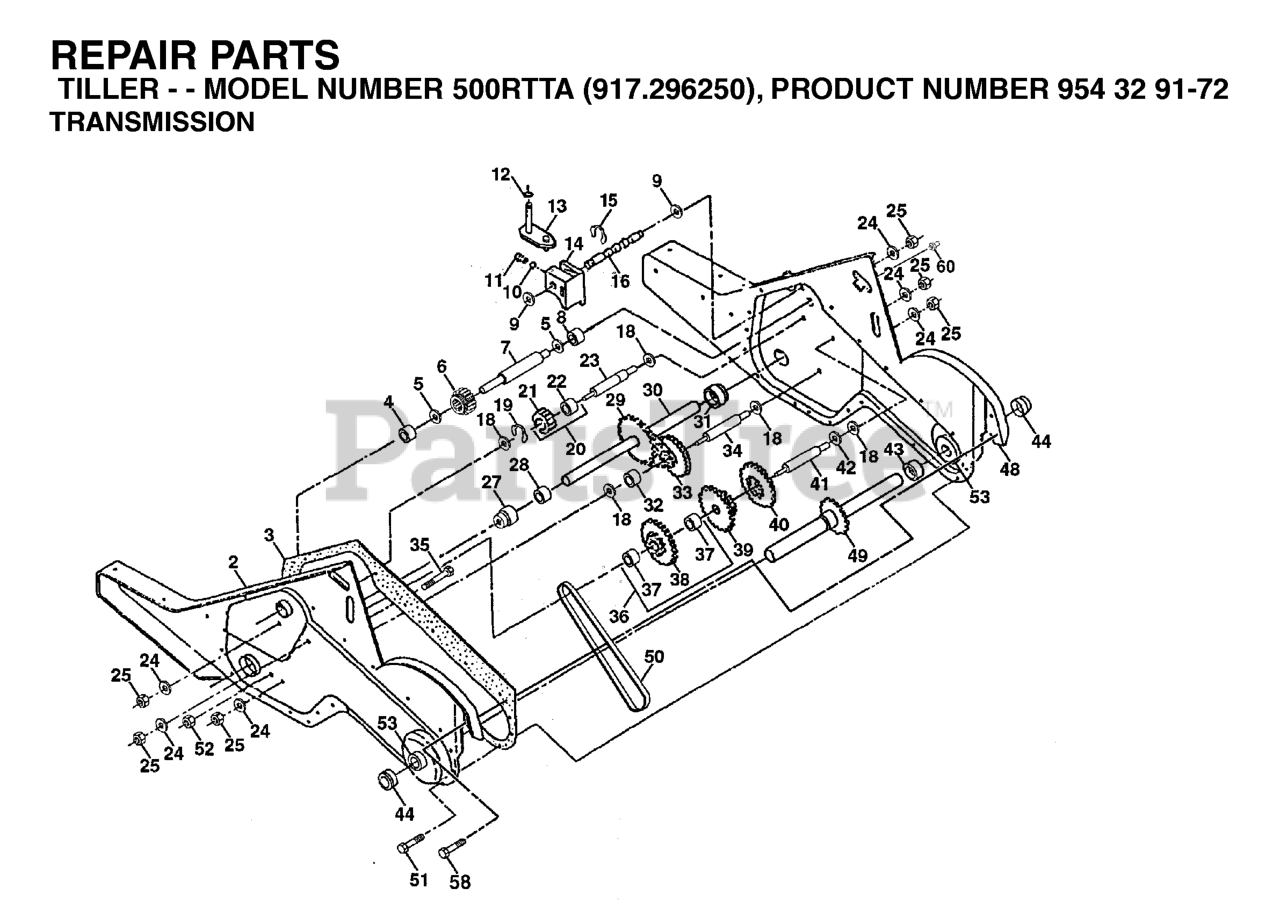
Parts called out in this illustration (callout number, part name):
1	TRANS SERV
2	GEAR CASE
3	GASKET
4	NEEDLE BRNG LT
5	THRUST WASHER
6	GEAR.PINION.INPUT
7	SHAFT.INPUT."D".TILLER
8	BEARING TI
9	WASHER, SEAL (2 2)
10	STEEL BALL KIT
11	SPRING-SHIFT CRT
13	BRACKET ASM.SHIFT.CRT
14	SHIFT FORK TI
16	SHAFT.SHIFTER.TILLER
20	GEAR ASSY CRT
21	GEAR-REV IDLR CRT
22	NEEDLE BEARING TI
24	LOCKWASHER
25	NUT.ASF.HEX.7/16
27	BEARING, SHAFT LH CRT
30	GROUND SHAFT ASS'Y
31	BEARING, SHAFT RH CRT
33	SPRCKT 8 GEAR CRT
34	SHAFT.SECONDARY.REDUCTION.CRT
35	SCRW WHIZ LOK CRT
36	SPROCKET.ASM.W/BEARING.TILLER
37	BEARING
38	SPROCKET, TINE
41	SHAFT.REDUCTION.TILLER
42	BRNG RACE T
44	SEAL ASM, OIL
48	GEARCASE, R.H. W/BEARING
49	TINE SHAFT
50	CHAIN.TILLER
51	SCREW
53	KIT.BEARING.TILLER.
58	BOLT SHOULDER 1/4-20 UNC X.875
60	ZERK M
